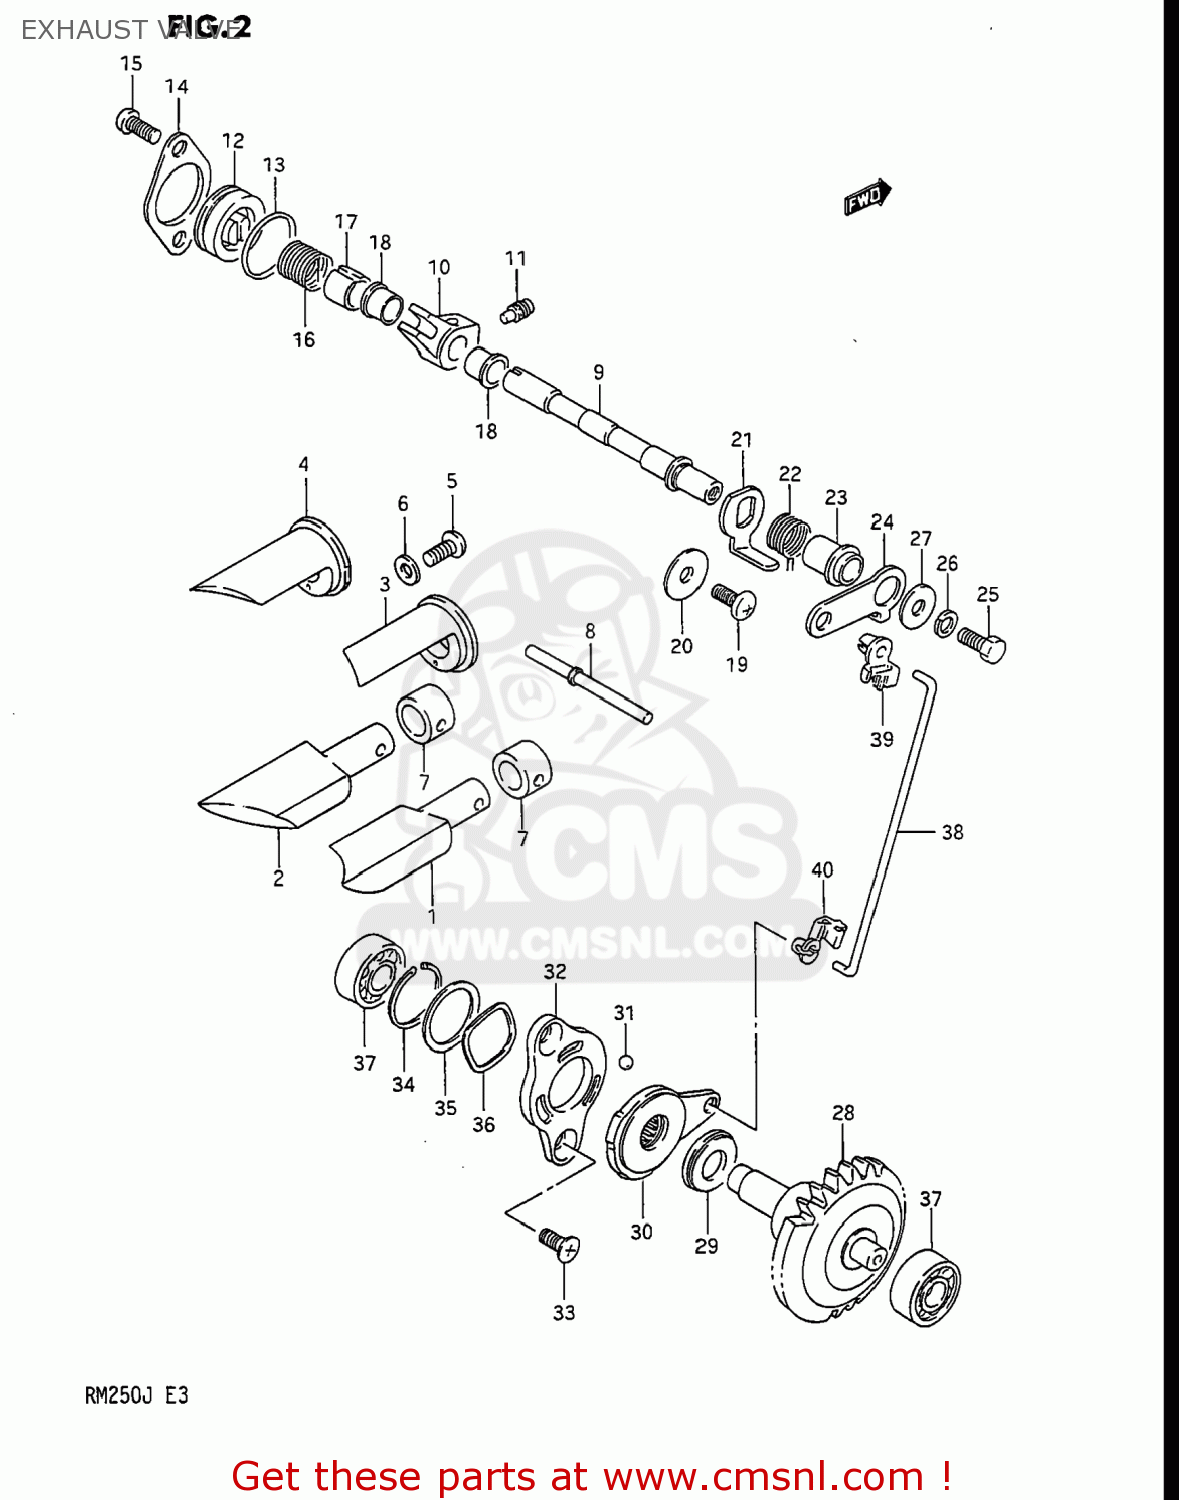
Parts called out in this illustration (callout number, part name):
1	VALVE,EXHAUST,R
2	VALVE,EXHAUST,L
3	GUIDE,EXHAUST VALVE,R
4	GUIDE,EXHAUST VALVE,L
5	SCREW
6	WASHER
7	HOLDER,EXHAUST VALVE
8	PIN,EXHAUST VALVE 48.5MM
9	SHAFT,EXHAUST VALVE
10	ARM,EXHAUST VALVE SHAFT
11	SCREW
12	CAP,EXHAUST VALVE
13	O RING(D:1.9,ID:22.6)
14	RETAINER,EXHAUST VALVE
15	SCREW
16	SPRING
17	SPACER,EXHAUST VALVE SPRING
18	BUSH
19	SCREW 6X12
20	WASHER
21	LEVER,EXHAUST VALVE NO
22	SPRING
23	SPACER,EXHAUST VALVE
24	LEVER,EXHAUST VALVE NO
25	BOLT
26	LOCK WASHER
27	WASHER (5.5X16X1.2)
28	GOVERNOR ASSEMBLY,EXHAUST
29	BEARING(10X22X2.8)
30	ACTUATOR,EXHAUST VALVE
31	BALL
32	STARTER,EXHAUST VALVE ACTUATOR
33	SCREW(5X10)
34	CIRCLIP
35	SHIM(19.1X25X0.3)
36	WASHER
37	BEARING(8X22X7)
38	ROD,EXHAUST VALVE
39	BUSH,EXHAUST VALVE ROD NO.1
40	BUSH,EXHAUST VALVE ROD NO.2
